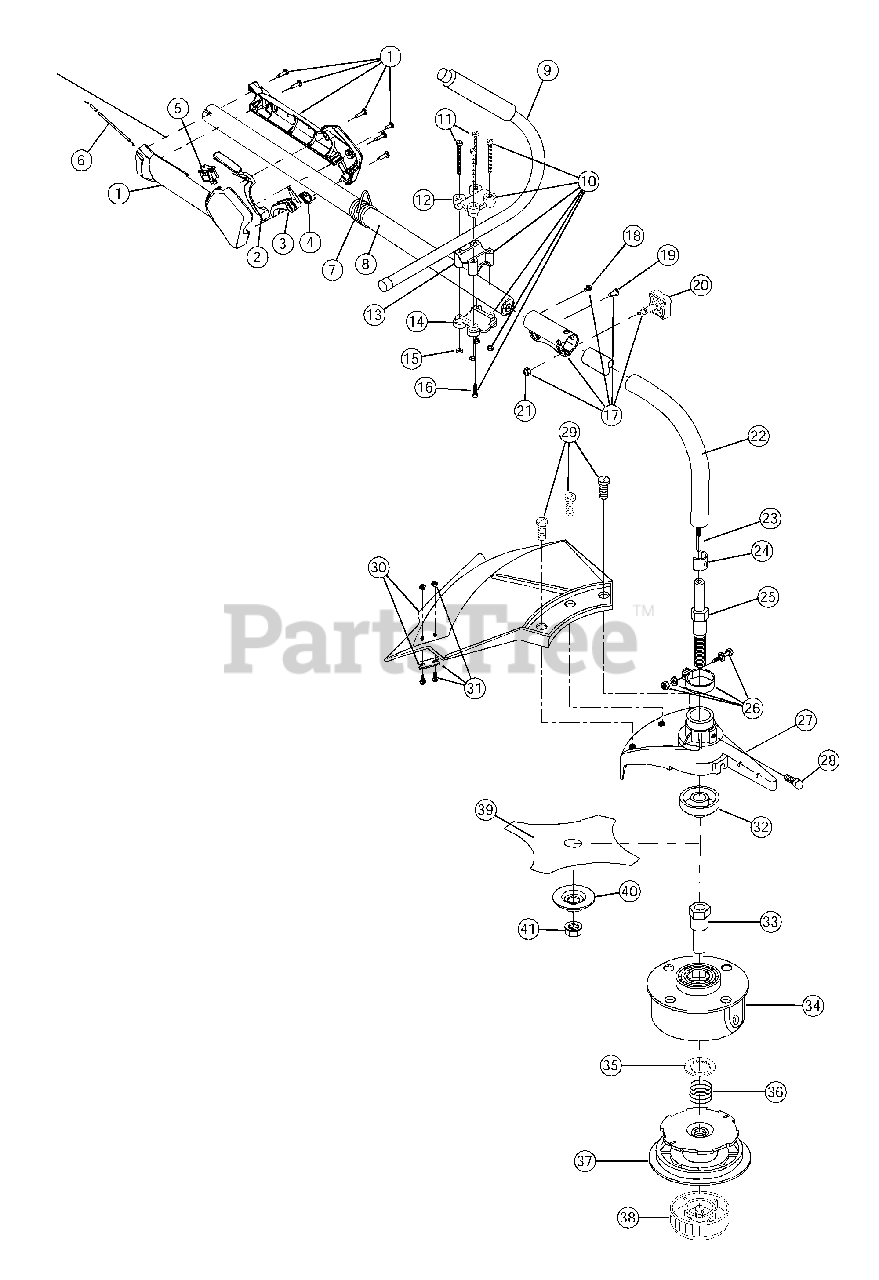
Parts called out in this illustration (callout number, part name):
1	Throttle Housing and Trigger Assembly
2	Throttle Trigger Lock-Out
3	Throttle Trigger
4	Throttle Trigger Spring
5	Switch Assembly
6	Throttle Cable Assembly
7	Harness Clip
8	Upper Drive Shaft Housing Assembly
9	J-Handle Assembly
10	Handle Bracket Assembly
12	Upper Handle Clamp
13	Middle Handle Clamp
14	Lower Handle Clamp
16	Anti-Rotation Screw
17	EZ-Link Coupler
20	Adjustment Knob
21	Knob Retaining Nut
22	Lower Drive Shaft Housing Assembly
23	Lower Flexible Drive Shaft
24	Retainer Sleeve
25	Output Shaft
26	Clamp Assembly
27	Bearing Housing Assembly
28	Mounting Bolt
29	Shield Mounting Screw
30	Shield and Blade Assembly
31	Blade Assembly
32	Shaft Bushing
33	Spool Shaft
34	Outer Spool
35	Retainer
36	Spring
37	Inner Reel
38	Bump Head Knob Assembly
39	4-Tooth Blade
40	Retaining Washer
